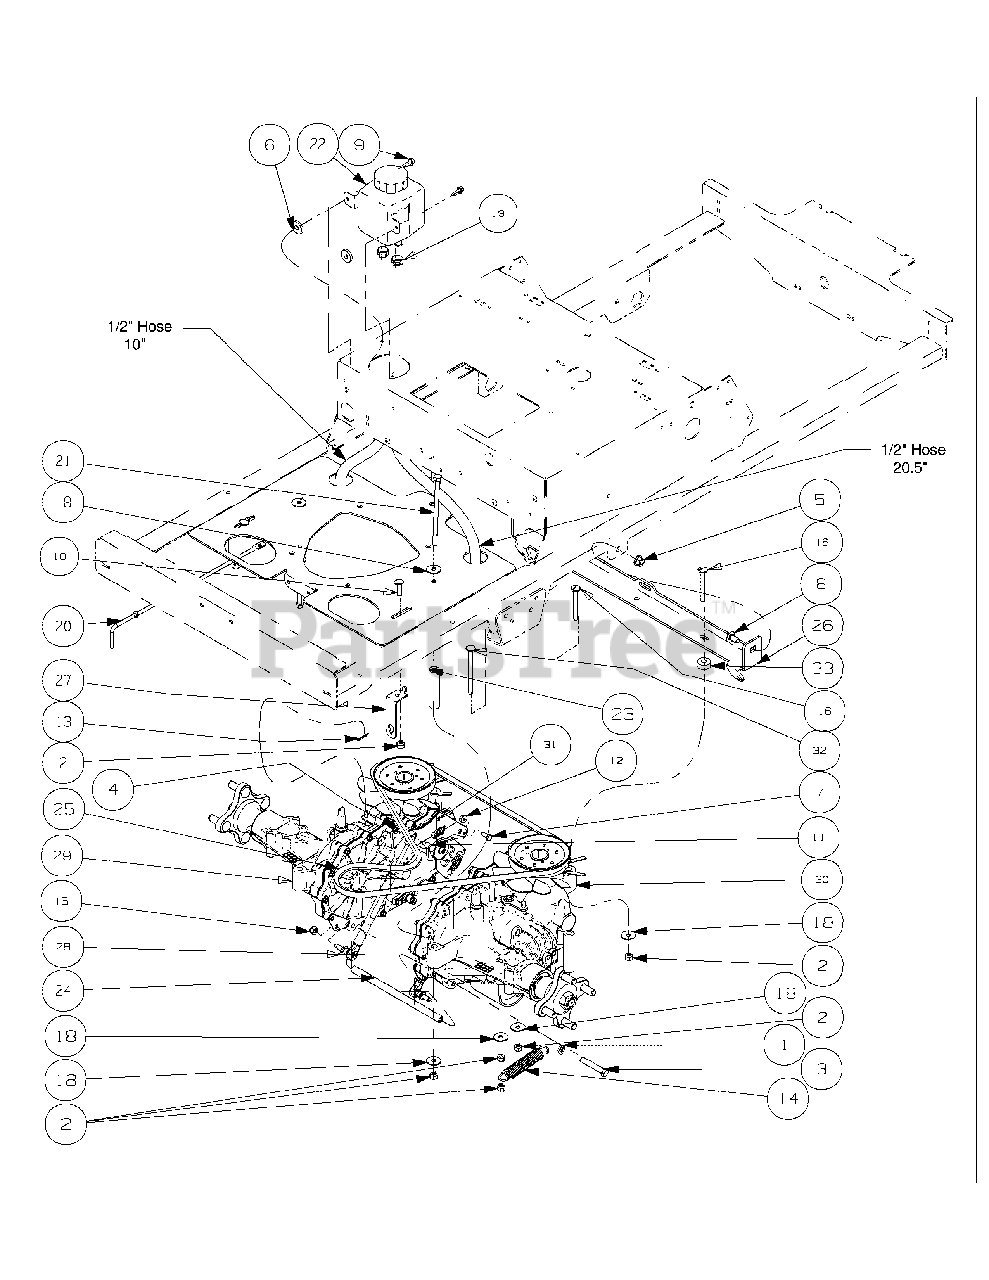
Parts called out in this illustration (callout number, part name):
1	Lock Washer, 3/8 Zinc
2	Nylock Nut, 5/16-18
3	Hex Cap Screw, 3/8-16 x 2.00
4	Nut, 1/4-28, SS, Nylon Insert
5	Nut, Flange Lock, 3/8-16
6	Idler Washer
7	Hex Cap Screw 1/4-20 x .620
8	Carriage Bolt, 3/8-16
9	Self Tapping Screw, 1/4-20 x .75
10	Carriage Bolt, 5/16-18 x 1.00
11	Shoulder Screw, 1/4-28
12	Nut, 1/4-20, Hex Flange Lock Nut
13	Cotter Pin, .072 x 1.12 Lg
14	Extension Spring, .865 OD x 4.68 Long
15	Nut, Hex, Center Lock, M8
16	Carriage Bolt, 5/16-18 x 2.75
17	Fuel Hose, .50 ID x .75 OD (30.5 inches)
18	Washer, 5/16 x 1.06
19	Hose Clamp
21	Hex Cap Screw, 5/16-18 x 6.00
22	Hydraulic Tank
23	Spacer, .375 ID x .75 OD x 3.30
24	Transmission Support Tube
25	V-Belt, 58.4
26	Transmission Front Mounting Bracket
27	Neutral Bracket
28	Cylinder Return to Neutral
29	IZT Transmission
30	IZT Transmission
31	Return to Neutral Bracket
32	Carriage Bolt, 5/16-18 x 4.00
33	Spacer .406 ID x 1.0 OD
